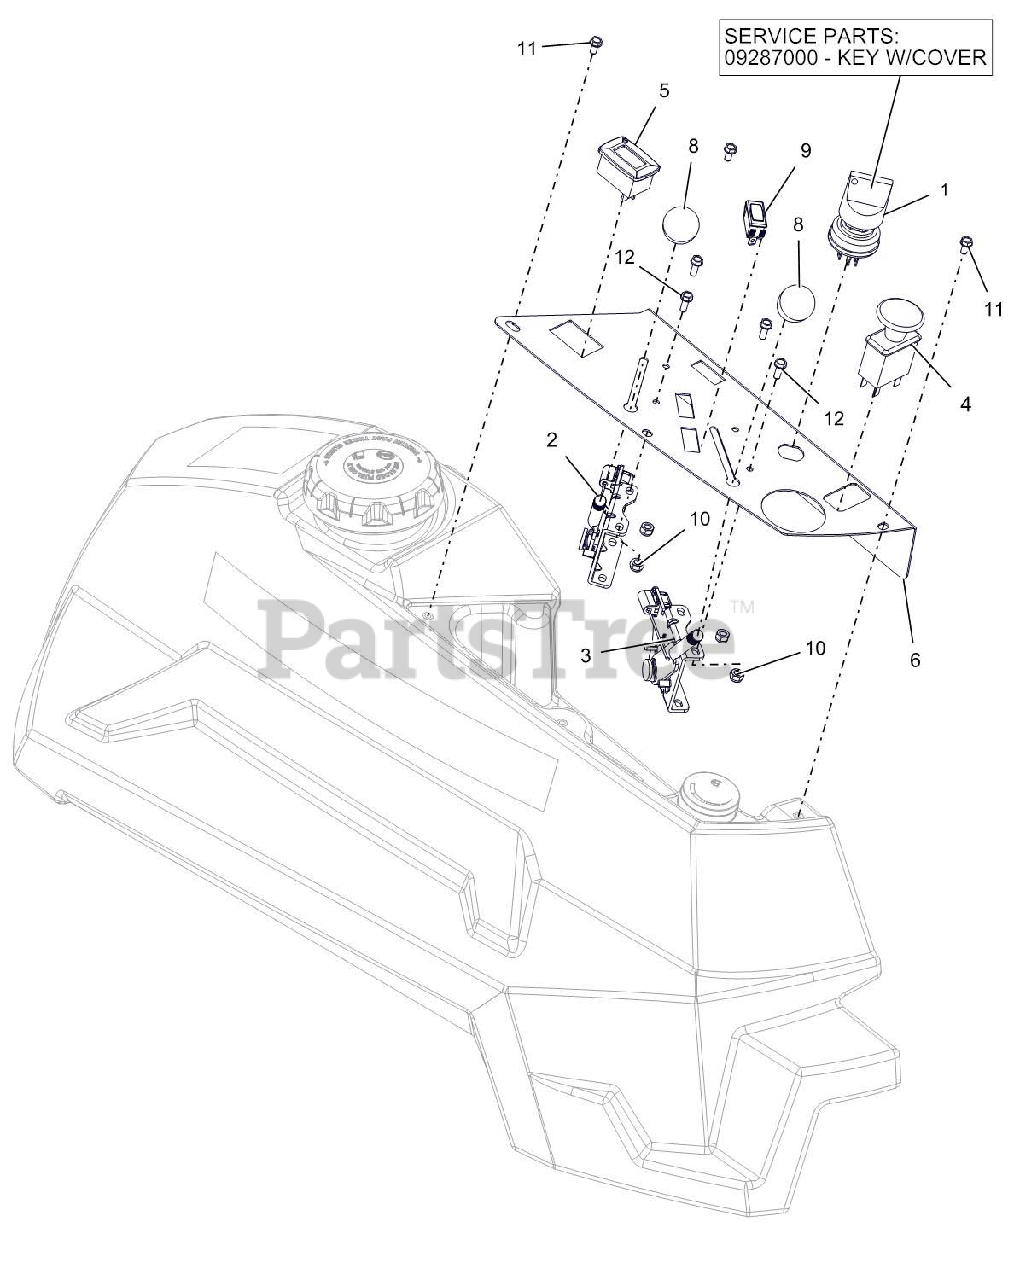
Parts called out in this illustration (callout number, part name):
1	KEY, W/ SHIELD
1	SWITCH, IGNITION
2	CABLE, PRO-CTRL 46.00"
3	CABLE, PRO-CTRL 53.00"
4	SWITCH, CLUTCH
5	METER, HOUR W/MAINTENANCE
6	PT400 CONTROL PANEL - RED
8	KNOB-CONTROL-BLACK .38-16X.50
9	LIGHT,INDICATOR
10	@NUT-LK-NYL 10-24 W/INSRT YWZC
11	SCR-MCH 10-24X.38 HWHSTAINLESS
12	@SCR-MCH 10-24X.50 HWH YWZC
